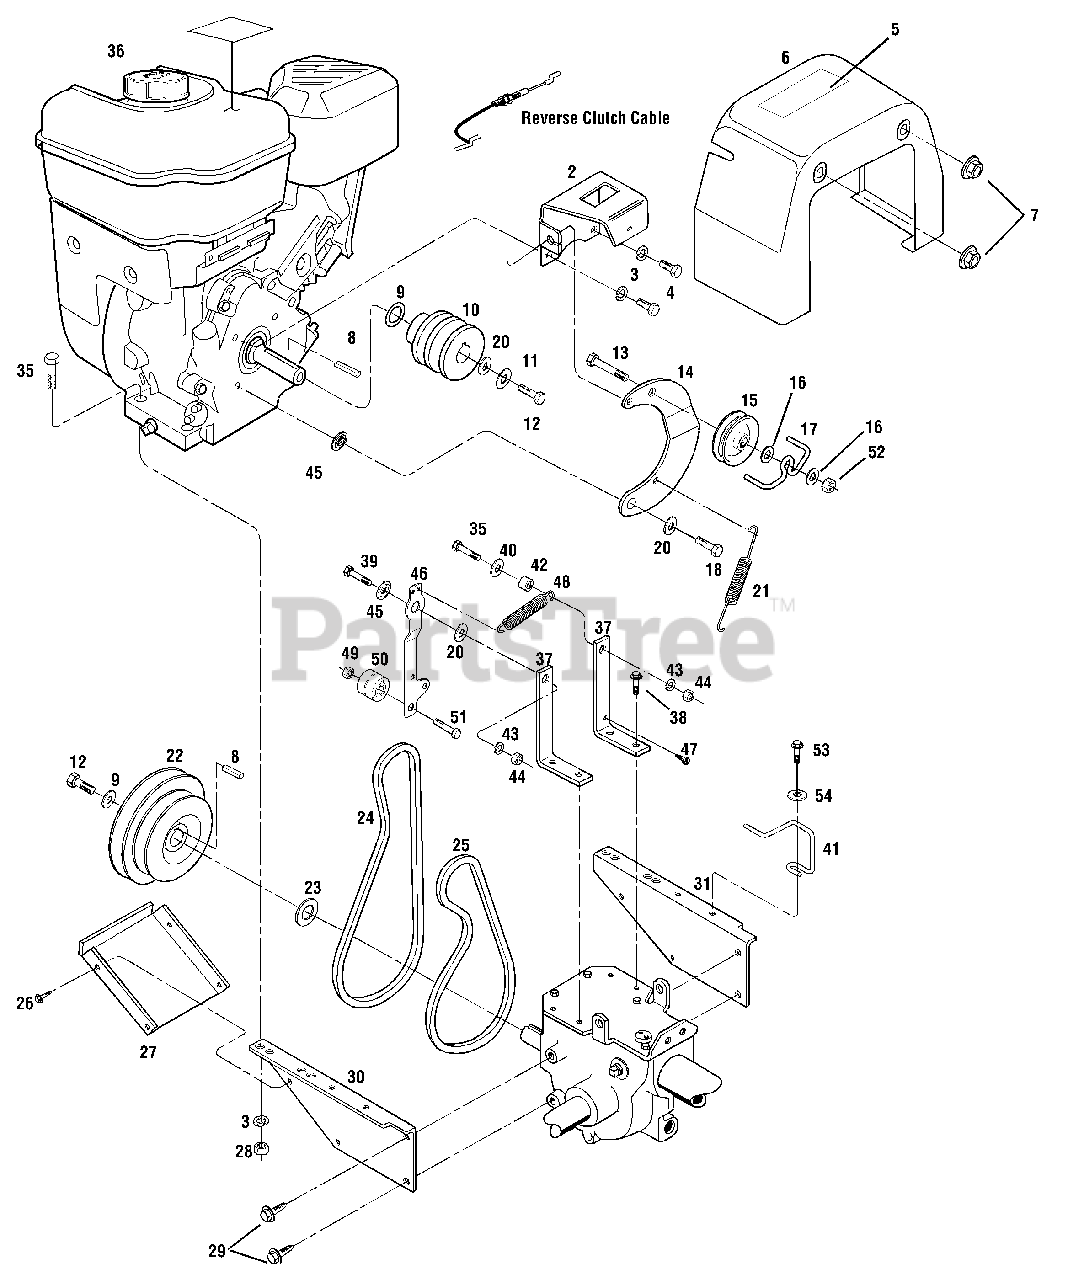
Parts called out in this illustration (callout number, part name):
2	Bracket, Clutch Cable
3	Lockwasher-5/16
4	Hex Hd. Screw, 5/16-24 x 1/2
5	Decal, Hot Surfaces/Belt Warning
6	Cover
7	Flange Lock Nut, 5/16-18
8	Key, 3/16 x 1-1/2
9	Shim
10	Pulley, Engine Drive
11	Belleville Washer
12	Hex Hd. Screw, 5/16-24 x 1-1/8
13	Hex Hd. Screw, 5/16-18 x 2
14	Reverse Idler Arm
15	Pulley, Reverse Idler
16	Flat Washer, 5/16
17	Belt Guide, Wire Formed
18	Hex Hd. Screw, 5/16-24 x 1
20	Washer, Flat, 1-1/8
21	Spring, Reverse Return
22	Transmission Pulley
23	Support Washer
24	Reverse Clutch Belt
25	Forward Clutch Belt
26	Self-tapping. Screw, #10-32 x 1/2
27	Guard, Belts/Pulleys
28	Hex Nut, 5/16-18
29	Hex Flange Screw, 5/16-18 x 3/4
30	Engine Support Bracket, left side
31	Engine Support Bracket, right side
35	Hex Hd. Screw, 5/16-18 x 1-1/2
36	Decal, Stabilization
37	Mounting Bar
38	Hex Flange Screw, 5/16-18 x 1
39	Hex Hd. Screw, 5/16-18 x 2-1/4
40	Flat Washer, 5/16
41	Belt Guide, Fwd Belt
42	Pivot Bushing
43	Lockwasher, 5/16
44	Hex Nut, 5/16-18
45	Washer, Shoulder
46	Idler Arm, Forward Tiller Direction
47	Screw, self tapping, #10-24
48	Spring
49	Hex Locknut, 5/16-18
50	Idler Pulley, Forward
51	Screw, 5/16-18 x 1-3/4
52	Hex Locknut, 5/16-18
53	Screw, 1/4-20 x 3/4
54	Flat Washer-1/4
